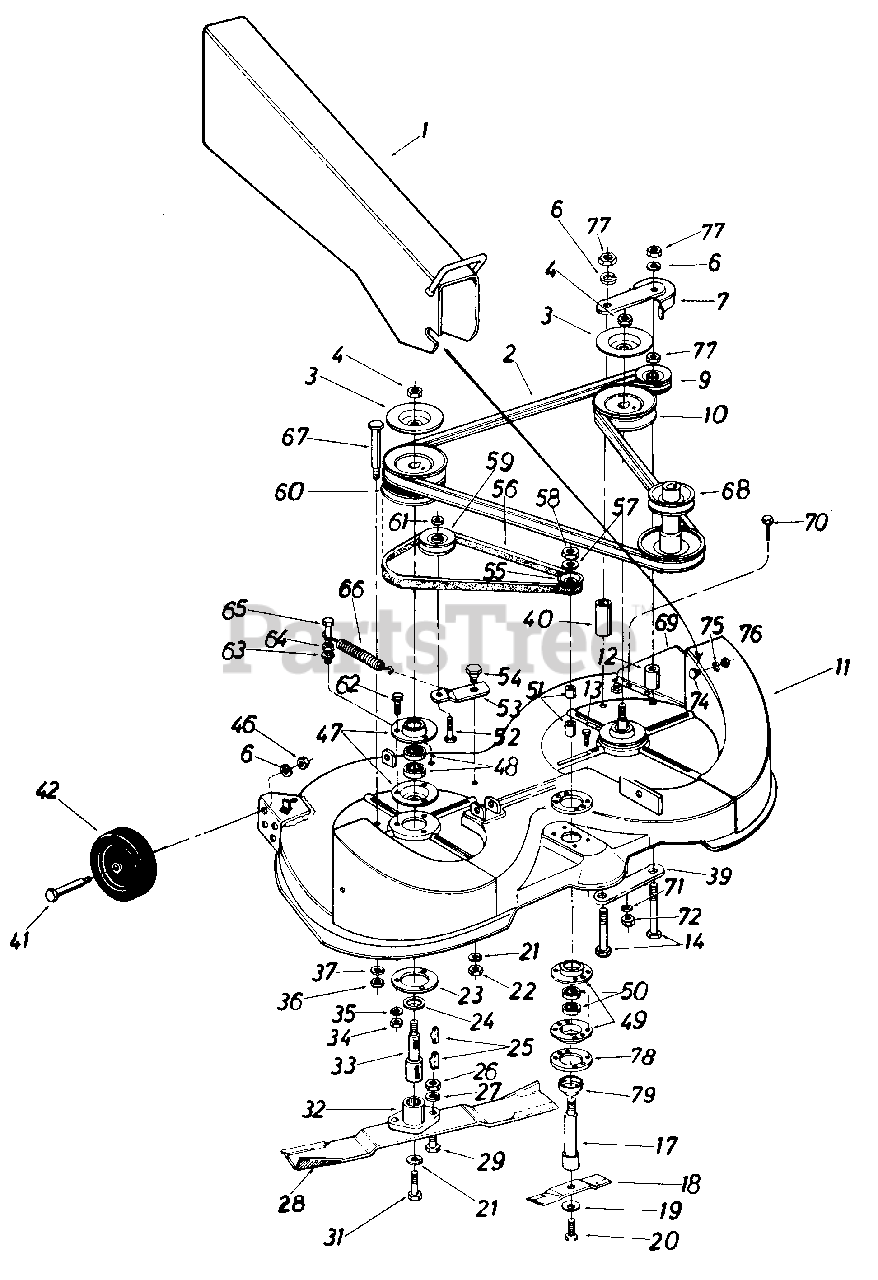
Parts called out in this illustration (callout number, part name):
1	Chute Extension Ass'y.-L.H.
2	"V"-Belt
3	Brake Disc
4	Hex Cent. L-Nut 5/8-11 Thd.
6	L-Wash. 3/8" I.D.
7	Idler Pulley Belt Guard Ass'y
9	5/8-V Belt Idler 3.50" O.D.
10	5/8-V Pulley-.628" I.D. x 5.25" O.D.
11	40" Rear Discharge Deck
12	Spacer .40" I.D. x 1.25" O.D. x 1.59" Lg.
13	Hex B-Tap Scr. 1/4" x 1.0"
14	Hex Bolt 3/8-24 x 3.75" Lg.
17	Blade Spindle
18	6.50" Blade
19	Bell-Wash. .40" I.D. x .88" O.D.
20	Hex Bolt 3/8-24 x .87" Lg.
21	L-Wash. 3/8" I.D.
22	Hex L-Nut 3/8-16 Thd.
23	Plate-Deck Reinforcement
24	Bearing Shield
25	#6 Hi-Pro Key 5/32 x 5/8" Dia.
26	Hex Nut 5/16-24 Thd.
27	L-Wash. 5/16" I.D.
28	20" High Lift Blade-R.H.
29	Hex Bolt 5/16-24 x 1.00" Lg. (Grade 5)
31	Hex Bolt 3/8-24 x 1.50" Lg. (Grade 5)
32	Blade Adapter Kit
33	Blade Spindle
34	Hex Nut 5/16-18 Thd.
35	L-Wash. 5/16" I.D.*
36	Hex L-Nut 3/8-16 Thd.
37	L-Wash. 3/8" I.D.
39	Reinforcement Plate
40	Spacer 3/8" I.D. x .50" O.D. x 2.72"
41	Shld. Bolt .498" Dia. x 1.53" Lg.
42	Cutting Deck Wheel
46	Hex Jam Nut 3/8-16 Thd.
47	Bearing Housing
48	Ball Bearing .787" I.D. x 1.85" O.D.
49	Bearing Housing
50	Ball Bearing .63" I.D. x 1.38" O.D.
51	Spacer .63" I.D. x .88" O.D. x.57" Lg.
52	Hex Bolt 3/8-16 x 1.251' Lg.
53	Idler Bracket
54	Shld. Bolt .625" Dia. x .170" Lg.
55	3/8" V-Pulley .628" I.D. x 2.00" O.D.
56	"V"-Belt
57	Bell-Wash. .63" I.D. x 1.05n O.D.
58	Hex Jam Nut 5/8-11 Thd.
59	1/2" V-Belt Idler 2.625" O.D.
60	Double Pulley
61	Hex Top L-Jam Nut 3/8-16 Thd.
62	Hex Sems Bolt 5/16-18 x 1.00" Lg.
63	L-Wash. 1/4" I.D.
64	Hex Nut 1/4-20 Thd.
65	Hex Bolt 1/4-20 x 1.00" Lg.
66	Ext. Spring .50" O.D. x 3.97" Lg.
67	Shld. Bolt .498" Dia. x 2.63" Lg.
68	Two Step Engine Pulley
69	Inner Chute Extension-L.H.
70	Hex Sems Scr. 1/4-28 x .62" Lg.
71	L-Wash. 1/4" I.D.
72	Hex Nut 1/4-28 Thd.
74	Shld. Scr. .500" Dia. x .218
75	L-Wash. 3/8" I.D.
76	Hex Jam Nut 3/8-16 Thd.
77	Hex Nut 3/8-24 Thd.
78	Reinforcement Plate
79	Bearing Shield
